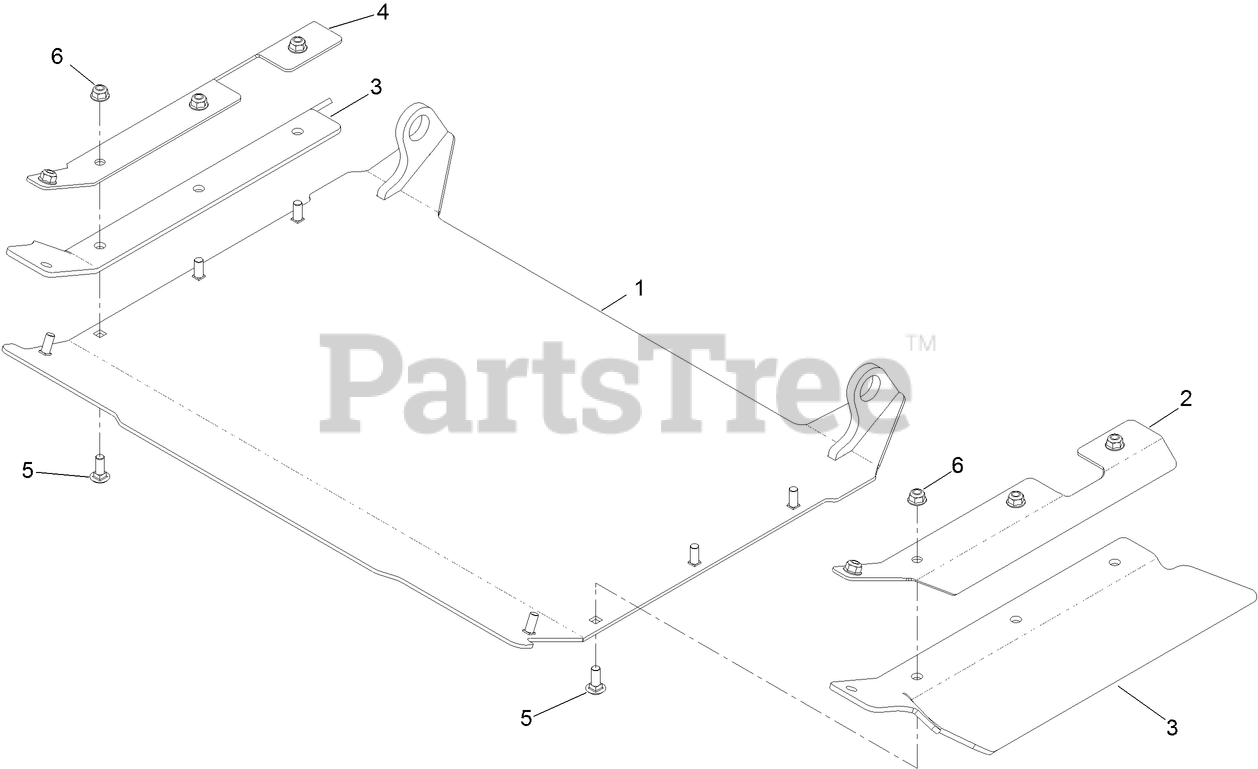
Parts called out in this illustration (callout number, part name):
1	TUNNEL-DISCHARGE
2	BRACKET-FLAP, LH
3	FLAP-RUBBER
4	BRACKET-FLAP, RH
5	SCREW-CARR
6	NUT-HF, NI
